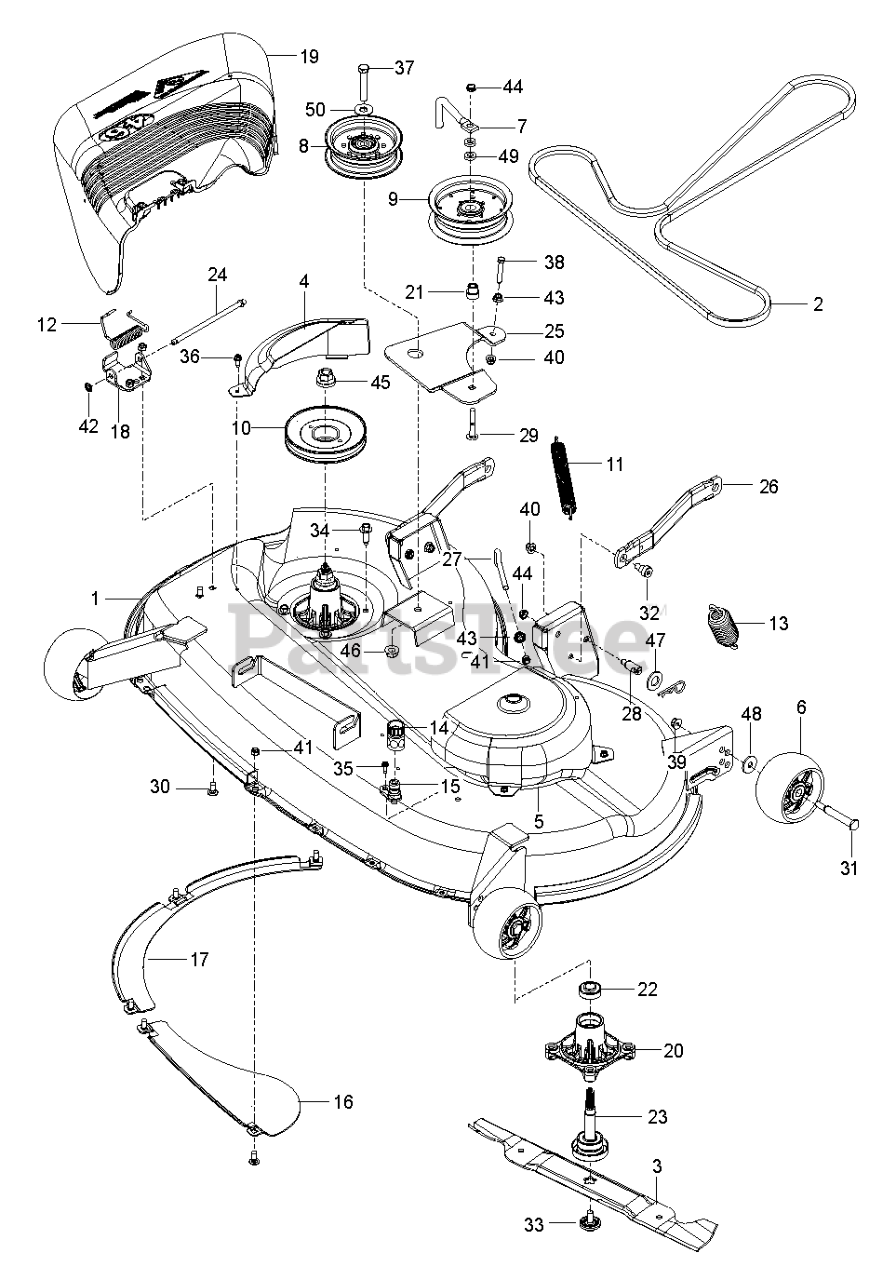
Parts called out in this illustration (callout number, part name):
1	KIT.46"DECK.W/PACKAGING&DECAL
3	BLADE.MOWER.46".HI.LIFT
4	COVER 46 XFAB TRACTOR RH MANDR
5	COVER.MANDREL.LH.46"
6	WHEEL.GAUGE.RALLY
7	BELT KEEPER 5"
8	PULLEY.IDLER.MWR.STATIONARY.LH
9	PULLEY, IDLER
10	PULLEY.MANDREL.46"
11	SPRING.EXTENSION
12	SPRING, TORSION
13	SPRING
14	COUPLING.QUICK CONNECT
15	PORT.WASHOUT
16	BAFFLE CENTER FRONT
17	BAFFLE FRONT RH
18	BRKT.DEFLECTOR.38"2005+
19	SHIELD.DEFLECTOR.MOWER.46"BLAC
20	MANDREL.W/SPCR.BRG.SHRT.NONRVL
21	IDLER BUSHING
22	BEARING.MANDREL.TOP.EXTENDED
24	Rod Hinge 42" 6 75 Wlg (AYP part number)
25	ARM.PNT.CLTCHG.STMP.46.RZ.EDIP
26	ARM.SUSPENSION.MOWER
27	EYE BOLT 5/16 X 3.50
28	STUD.FASTNER.W/ANTI-ROTATE
29	Bolt, Carriage 3/8-16 x 2 1/4 (AYP part number)
30	BOLT 5/16C X 3/4" CARRIAGE
31	BOLT.SHOULDER.3/8-16X3-5/8.
32	SB 3/8-16 X 3/8 SKT HD ZD
33	SCREW.SEMS.7/16-20X1.HEX.HEAD
34	BOLT.HEX.WASHR.HED.313-18X1.19
35	SCREW #10 X 1/2 SELF TAPPING
36	Screw Hex Thd Cut 1/4-20x5/8 T (AYP part number)
37	BOLT.HEX.7/16-14
38	BOLT.5/16-18X1-1/4 FULL THD
39	NUT LOCK FLG 3/8-16 UNC
40	5/16-18 NYLOC FLANGE NUT
41	Locknut, Hex, with Washer Insert 5/16-18 (AYP part number)
42	Nut Push Phos & Oil (AYP part number)
43	NUT 5/16C WHIZ
44	NUT HEX 3/8-16 NYLON, THIN
45	NUT.FLANGE.LOCK.TOP
46	NUT.LOCK.FLANGE.7/16
47	WASHER
48	WASHER 5/16 FLAT
49	WASHER 3/8 X 3/4 X .187 TK
50	WASHER 7/16 FLAT ZD
